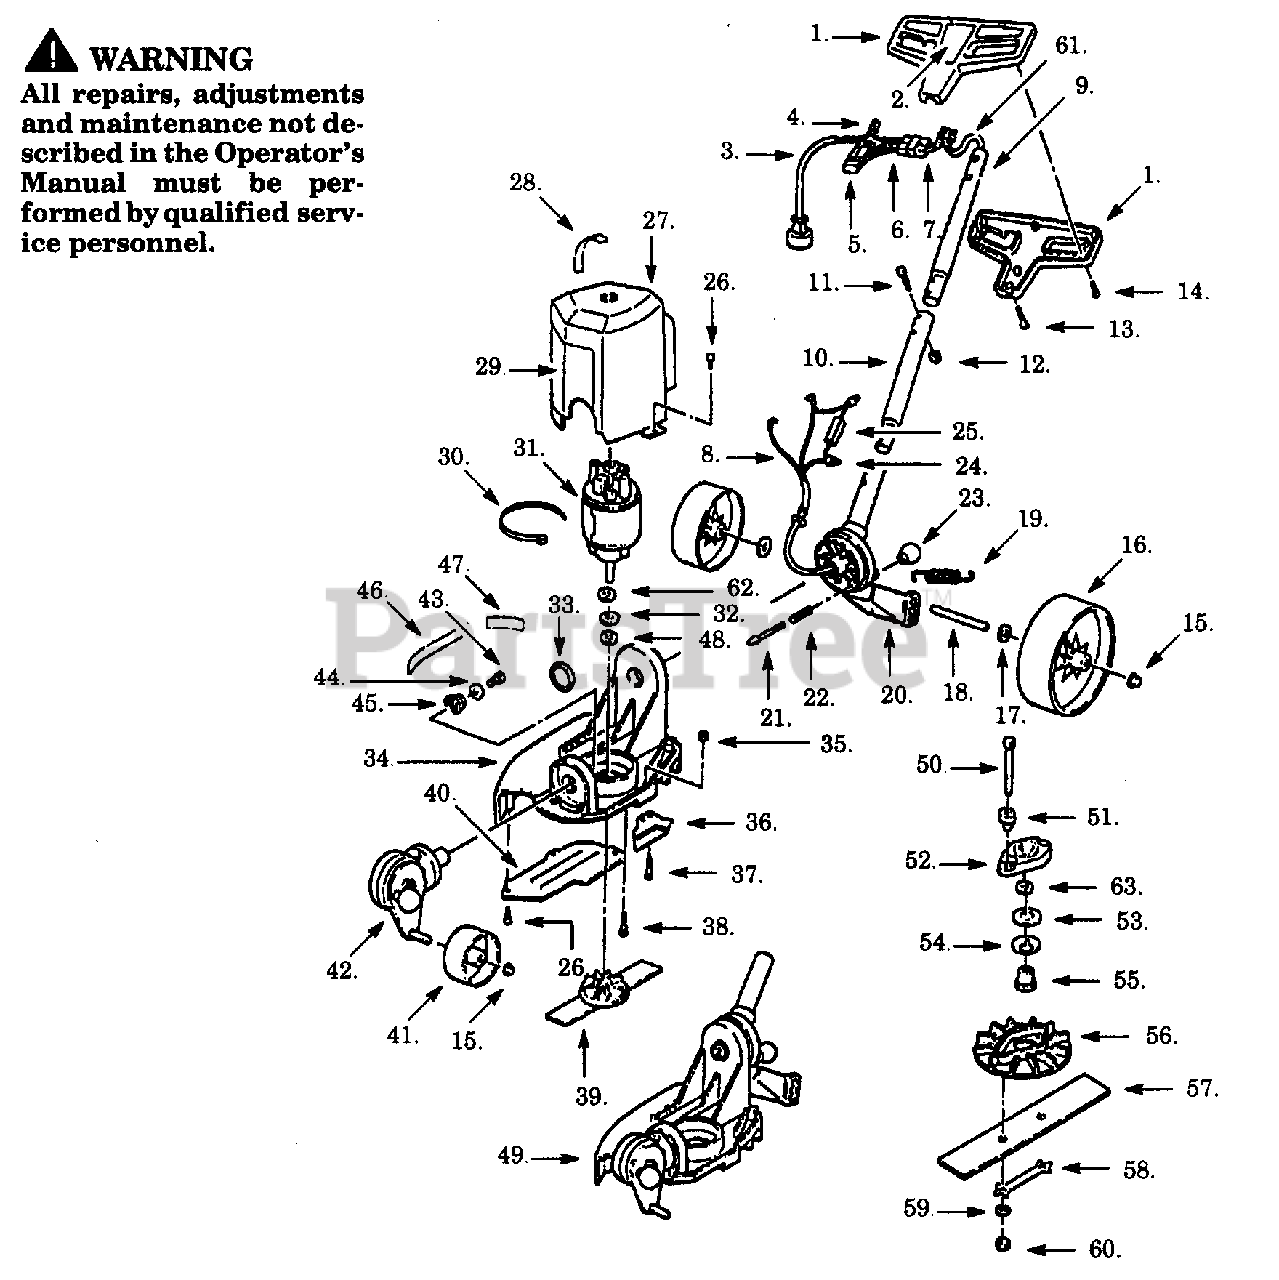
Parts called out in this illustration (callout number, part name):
1	Handle Set
2	Handle Label (Not a serviceable part)
3	Power Cord
4	Wire Nut
6	Bridge Ass'y.
7	Insulator Shield
8	Harness Ass'y.
9	Upper Tube
10	Lower Tube
12	Locknut
15	Push Nut
16	Rear Wheel
18	Rear Axle
20	Rear Swivel
21	Swivel Lock Shaft
22	Swivel Lock Spring
24	Terminal Cap
25	Resister
27	Motor Cover
28	Rear Adjust Label (Not a serviceable part)
29	Motor Cover Label (Not a serviceable part)
30	Tie Wrap
31	Motor Ass'y.
33	Retaining Ring
34	Deck Frame
36	Blade Guide
39	Blade Ass'y.
40	Side Guard Plate
41	Front Wheel
42	Front Swivel Ass'y.
45	Front Swivel Spring
46	Dyn Brake Label (Not a serviceable part)
47	Warning Label (Not a serviceable part)
49	Edger Frame Ass'y.
51	Insulating Sleeve
52	Clutch Plate
54	Spring Washer
55	Clutch Sleeve
58	Lock Strap
59	Lockwasher
61	Harness Ass'y.
62	Retaining Ring
